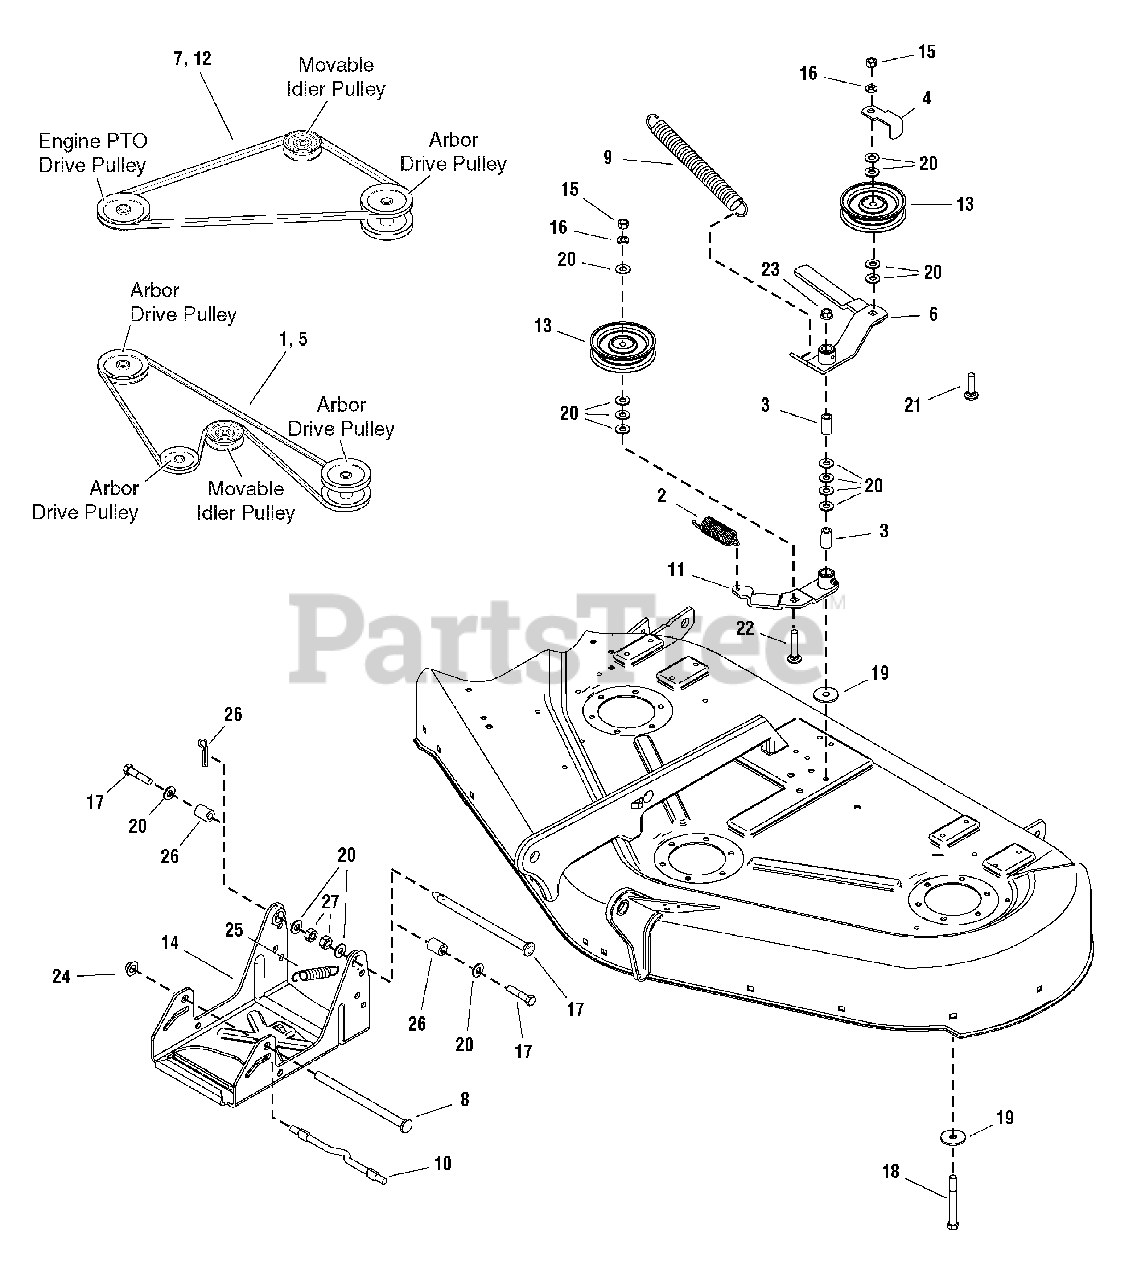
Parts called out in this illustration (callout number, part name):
1	BELT, 83.1 44"
2	SPRING, Extension
3	SPACER, Case Hard
4	GUARD, Belt
5	V BELT, Arbor Drive 50
6	LEVER ASSEMBLY, Idler w/Bushings & Fitting
7	V BELT, Mower Drive 50
9	SPRING, Extension
11	LEVER ASSEMBLY, Idler w/Bushings & Fitting
12	V BELT, HA 61.10 44"
13	PULLEY, Idler
14	HITCH, Mower 44, 50"
15	NUT, Hex 3/8-16 NC-2B
16	LOCKWASHER, Spring 3/8
17	CAPSCREW, Hex Head, 3/8-16 x 1-3/4
17	PIN, Hitch
18	CAPSCREW, Hex Head 3/8-16 x 3-1/2 G5
19	WASHER, 3/8
20	WASHER, 3/8
21	CARRIAGE BOLT, 3/8-16 x 1-1/2 G5
22	CARRIAGE BOLT, 3/8-16 x 2 G5
23	NUT, Hex Flange 3/8-16 Machine Lock
24	NUT, Push
25	SPRING, Extension
26	SPACER
26	PIN, Click
27	NUT, Hex Toplock Spiral Lock Flange 3/8-16
